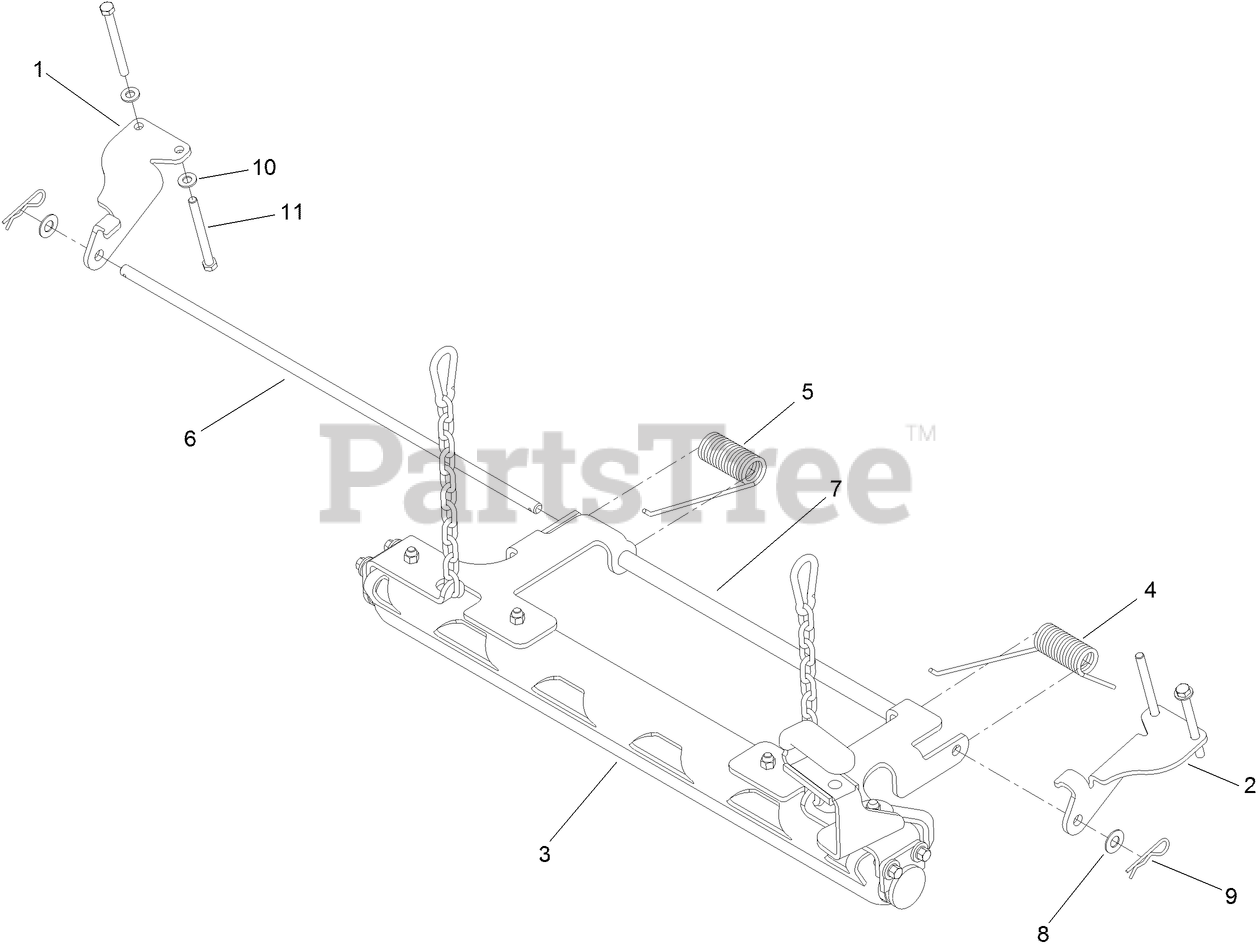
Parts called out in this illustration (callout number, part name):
1	BRACKET-STRIPER MOUNT, LH
2	BRACKET-STRIPER MOUNT, RH
3	ROLLER ASM
4	SPRING-TORSION
5	SPRING-TORSION
6	ROD-PIVOT
7	TUBE-PIVOT
8	WASHER-PIVOT
9	PIN-COTTER
10	WASHER-FLAT
11	SCREW-HH
